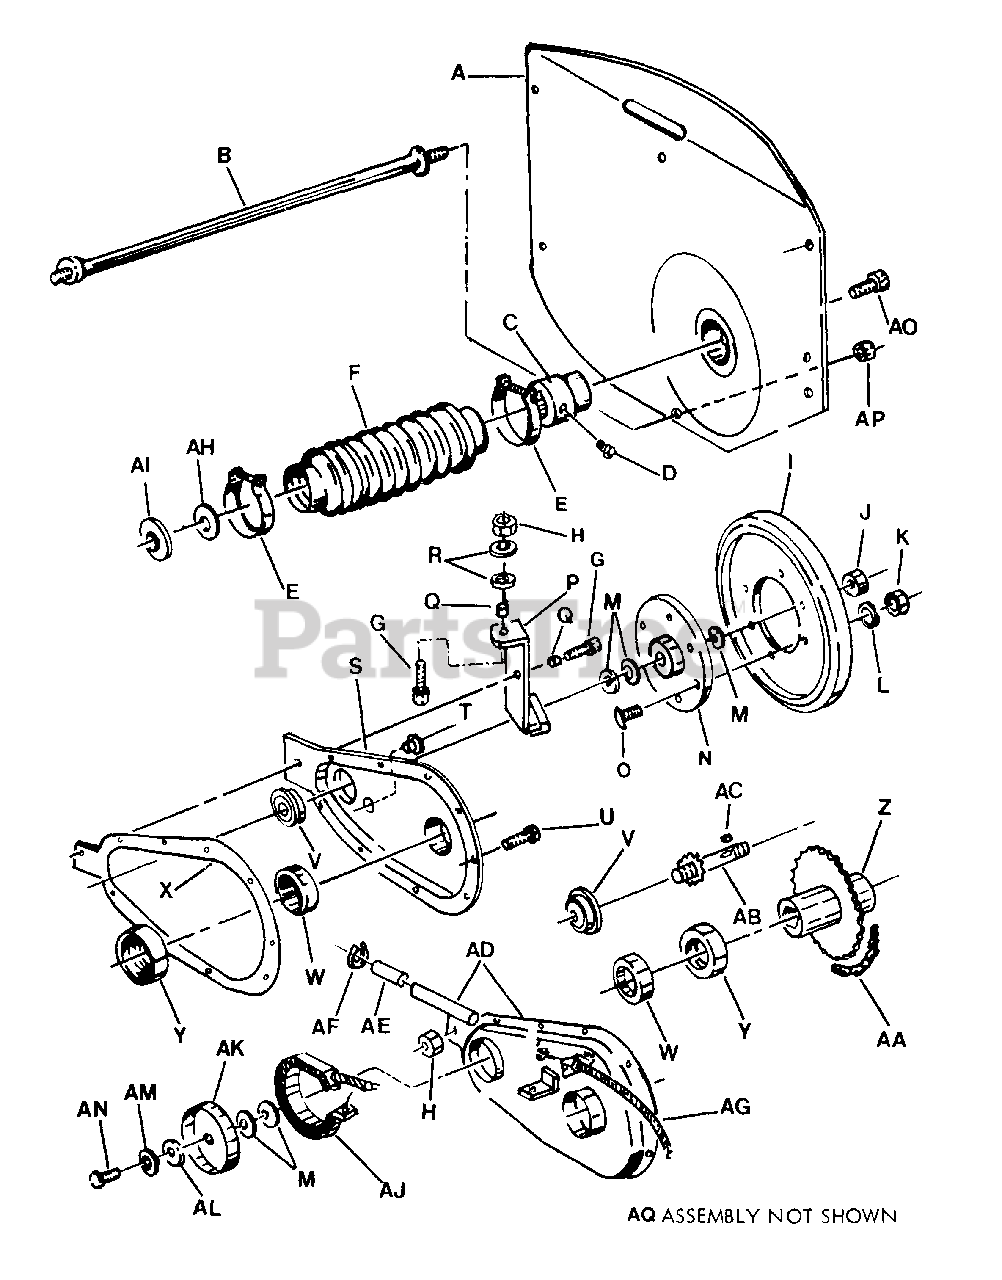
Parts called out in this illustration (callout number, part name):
A	FENDER, LEFT HAND
B	ROD, CROSS TIE
C	BEARING, L. H. FENDER
D	FITTING, GREASE
E	CLAMP, BOOT
F	BOOT, (CHAIN CASE SIDE)
G	SCREW, HEX HEAD CAP 1/4-28 x 3/4
H	NUT, HEX LOCK 1/4-28
I	DRIVEN DISC (R/B 7018782)
J	NUT, 5/8-18 HEX CENTER LOCK
K	NUT, 5/16-18 HEX
L	WASHER, 5/16 LOCK
M	WASHER, BELLEVILLE
N	HUB, DRIVEN - Disc (KIT)
O	BOLT, CARRIAGE 5/16-18 x 3/4
P	LEVER, BRAKE - ASSEMBLY
Q	SPACER, SPLIT
R	WASHER
S	COVER, L. H. CASE
T	PLUG, PLASTIC (CUP INSERT)
U	SCREW, #10-24 x 1/2" Hex Washer Self-Tap (Torx)
V	BEARING, SPROCKET SHAFT
W	BEARING, NEEDLE
X	GASKET, CHAIN CASE
Y	WASHER, NYLON THRUST
Z	HUB, SPROCKET
AA	CHAIN
AB	SHAFT, SPROCKET
AC	KEY, 1/8 x 5/8" Woodruff
AD	COVER, R. H. CASE
AE	ROLLER
AF	RING, RETAINING
AG	HOUSING, BRAKE CABLE
AH	WASHER, NYLON (Notched version = 7012271)
AI	WASHER, FLANGE
AJ	BAND, AUXILIARY BRAKE
AK	DRUM, AUXILIARY BRAKE
AL	WASHER, BRAKE DRUM
AM	WASHER
AN	SCREW, HEX HEAD CAP 3/8-24 x 1/2
AO	SCREW, SELF-TAPPING 5/16-18 x 5/8
AP	NUT, 5/16-24 HEX (CROSS TIE ROD)
